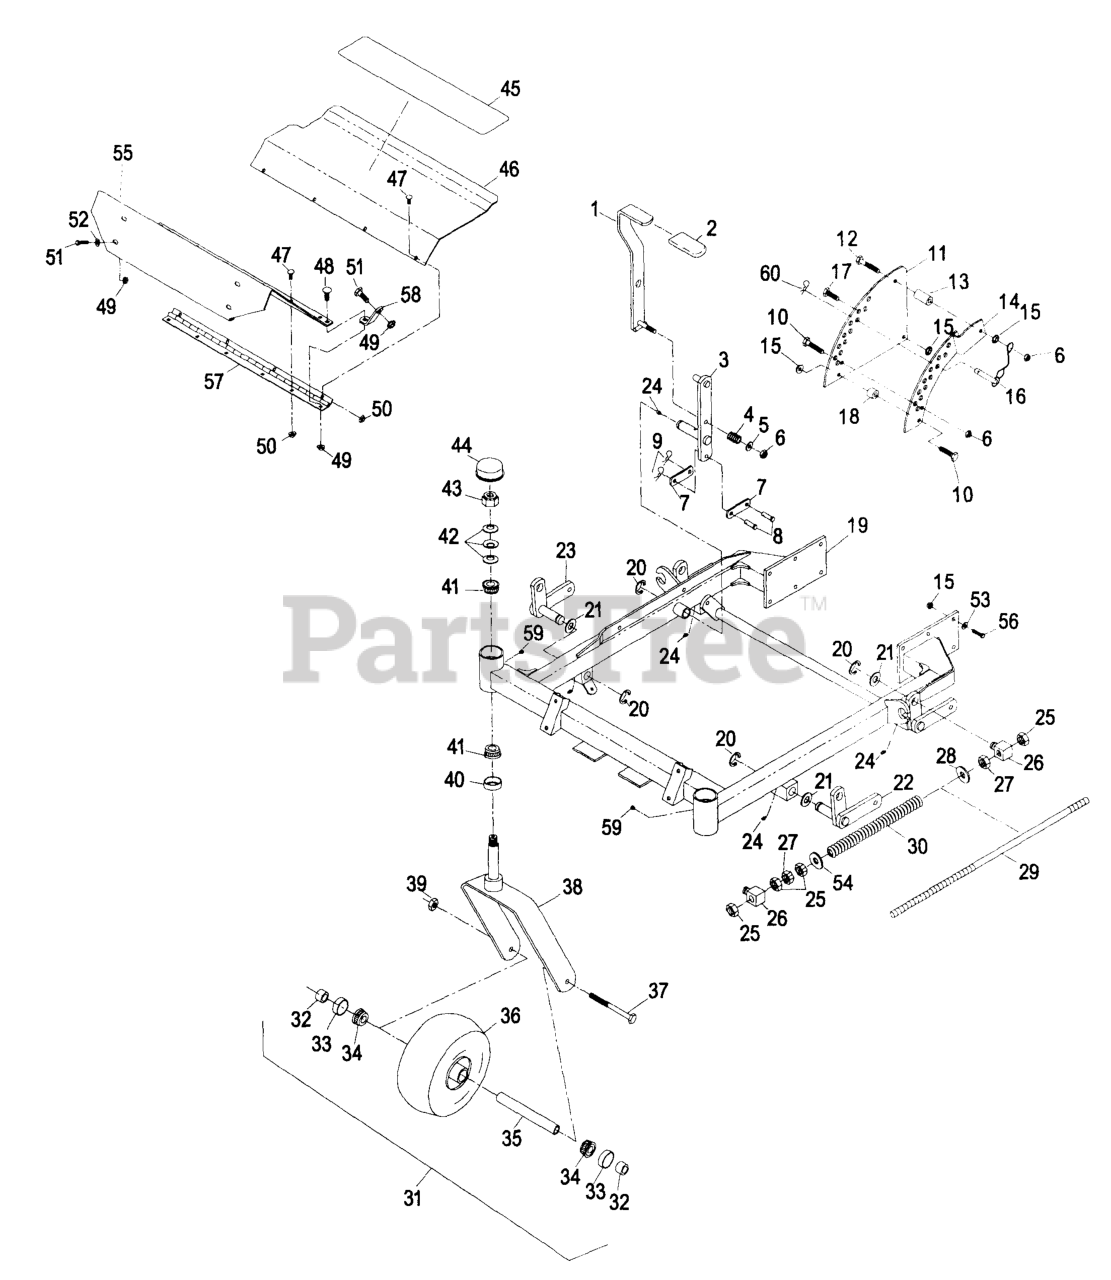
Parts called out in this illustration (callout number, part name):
2	GRIP-LEVER, LIFT
3	ARM-DECK, LIFT
4	SPRING-COMPRESSION
7	ARM-LIFT, DECK
8	PIN-CLEVIS
9	PIN-COTTER
11	PLATE-LIFT, DECK
13	BUSHING-LEVER, LIFT
14	PLATE-LIFT, DECK
16	PIN-HITCH (W/LANYARD)
18	BUSHING-LEVER, LIFT
22	WLD,SHAFT LH
23	WLD,SHAFT RH
26	SWIVEL-DECK MOUNT, REAR
29	ROD-LIFT, DECK
30	SPRING-COMPRESSION
32	SPACER-BEARING
33	SEAL-BEARING
34	BEARING-CONE, TAPERED ROLLER
35	SPACER-CASTER, FRONT
36	WHEEL AND TIRE ASM
40	SEAL-GREASE
41	Cone-Bearing Tapered Roller
42	WASHER-BELLVILLE
44	CAP-GREASE
45	PAD-ANTISKID
57	HINGE-FLOORPAN
58	BRACKET,FLOOR PAN
60	PIN-COTTER
